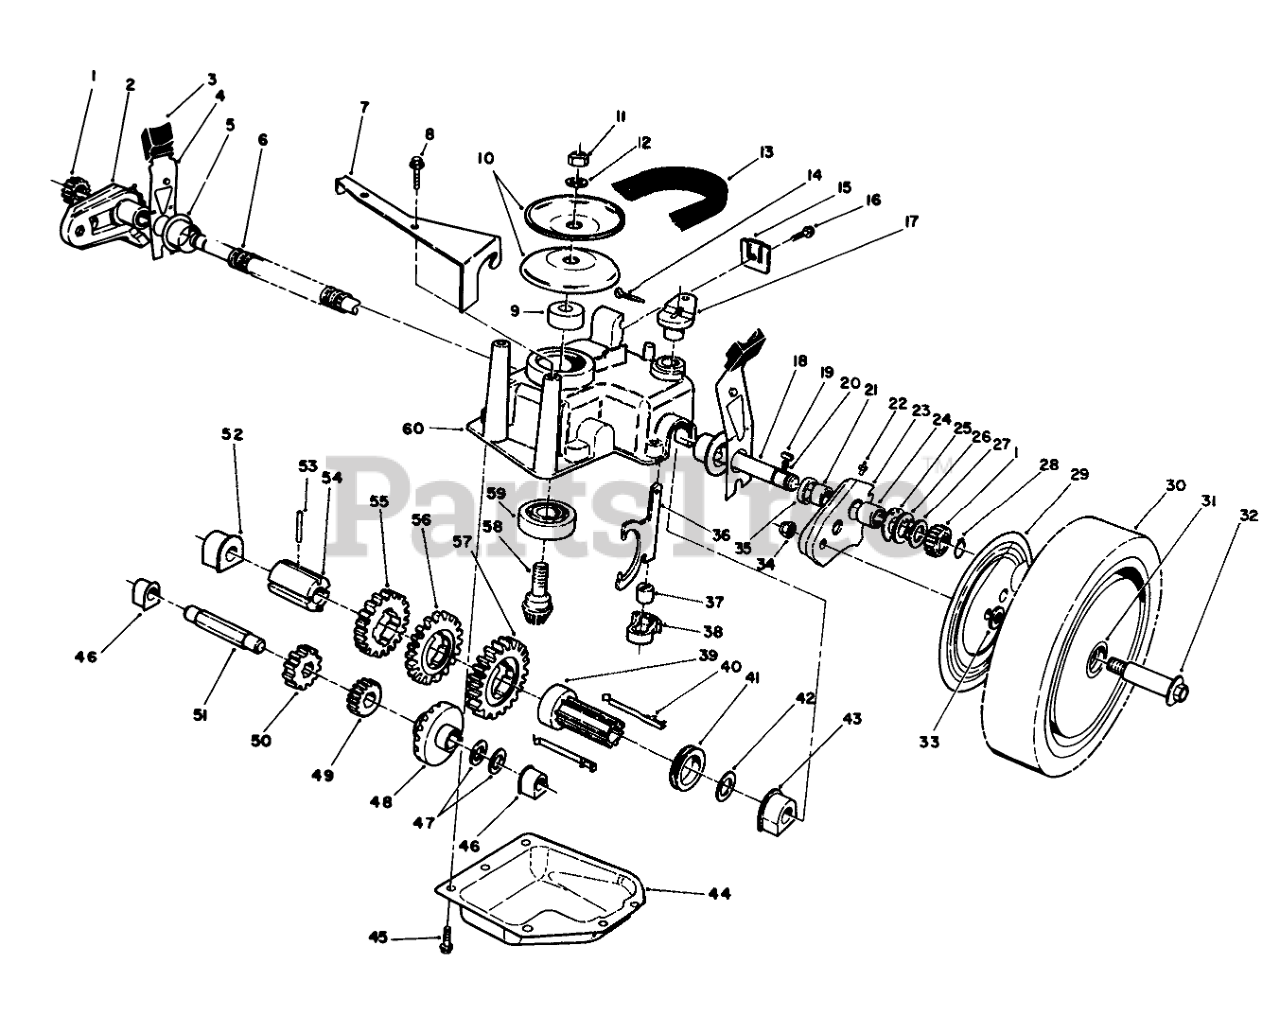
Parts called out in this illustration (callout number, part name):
1	GEAR-PINION
2	Pivot Arm Assembly-R.H. (Incl. Ref. #21, 22, 24 & 35)
3	KNOB-ARM
4	SPRING ARM ASM SP
5	CAP-END
6	CONDUIT-CONVOLUTED, SPLIT
7	Bracket-Guide
8	SCREW-HWHTF
10	Pulley Half
11	NUT-HEX
12	WASHER-FLAT
13	V-BELT E
14	PIN-COTTER
15	Cable Clamp
16	SCREW-HWHTF
17	SHIFT LEVER
18	Output Shaft
19	KEY RECTANGULAR
20	SPRING-COMPRESSION
21	BUSHING
22	FITTING-GREASE
23	Pivot Arm Assembly-L.H. (Incl. Ref. #21, 22, 24 & 35)
24	BEARING-ROLLER
25	INNER THRUST WASHER
26	WASHER-THRUST, OUTER
27	WASHER-THRUST, OUTER
28	PIN-ROLL
29	WHEEL COVER
30	Wheel-Tire & Gear Assembly (Incl. Ref. #31)
31	BUSHING
32	WHEEL BOLT
33	WASHER
34	Nut
35	SEAL-OIL
36	YOKE-SHIFT
37	BUSHING-YOKE
38	RETAINER-FORK, SHIFT
39	Sleeve-Shift Key
40	Key Shift
41	SHIFT COLLAR
42	WASHER-PLAIN
43	BUSHING-OUTPUT
44	Cover-Gearcase
45	SCREW-HWHTF
46	BUSHING
47	WASHER-THRUST
48	Gear-Bevel
49	PINION-20T
50	PINION-25T
51	SHAFT-INTERMEDIATE
52	BUSHING
53	PIN-SPRING
54	SLEEVE-GEAR
55	GEAR-39T
56	GEAR-44T
57	GEAR-49T
58	Gear-Pinion
59	BEARING-BALL
60	CASE-GEAR, UPPER
